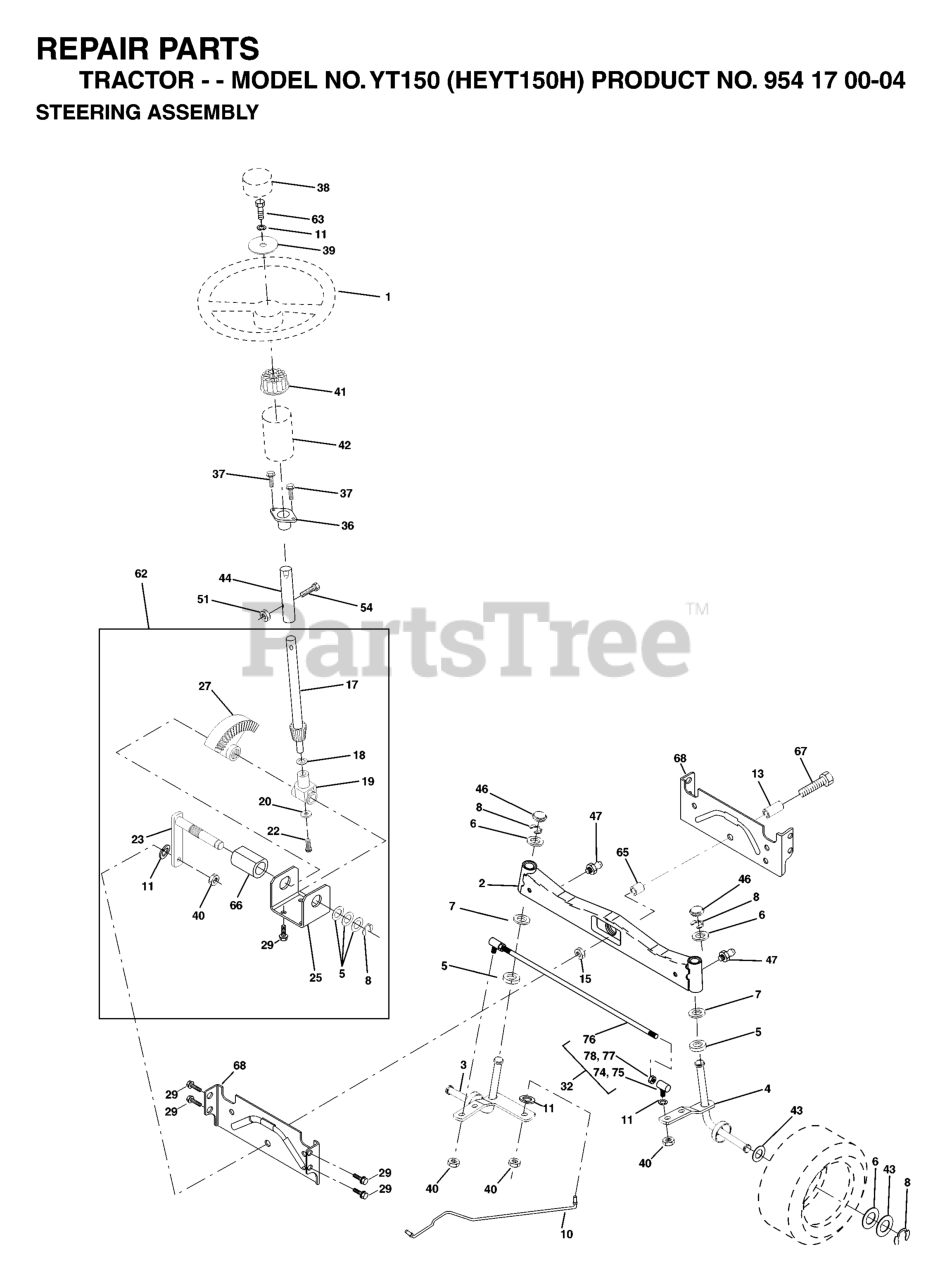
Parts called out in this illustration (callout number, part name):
1	STEERING WHEEL
2	FRONT AXLE ASSY
3	SPINDLE ASM LH
4	SPINDLE ASM RH
5	THRUST WASHER
9	BRNG T
10	LINK.DRAG.DROPPED.LT
11	WASHER, LOCK 3/8
13	BEARING AXLE
15	NUT-LOC,FLANGE LT
17	SHAFT ASM STEERING
18	THRUST WASHER
19	SHAFT,SUPPORT
20	WASHER
22	SCREW HEX SOCKET 1/4-20 X 5/8
23	SHAFT PITMAN
25	BRACKET STEERING
27	GEAR.SECTOR
29	SCREW
32	ROD ASSY/TIE BALL
36	BUSHING, STEERING
37	SCREW.TT.#10-32X.5.3/8.FLANGE
38	INSERT,STR WHEEL
39	WASHER T
40	GRIPCO NUT
41	ADAPTER LT
42	BOOT, STEERING
44	EXT SHAFT STEERING
46	CAP.SPINDLE.BLACK
47	ZERK M
51	NUT.71038.31-18.HEX.NYLOCK
54	BOLT.5/16-18X1-1/4 FULL.THREAD
62	KIT, STEERING ASSEMBLY
65	SPACER AXLE
66	BEARING ARM
67	Bolt, Hex 5/8 -11 x 2 - 3/4 Gr. 5
68	AXLE, BRACE
74	JOINT
76	TIE ROD
